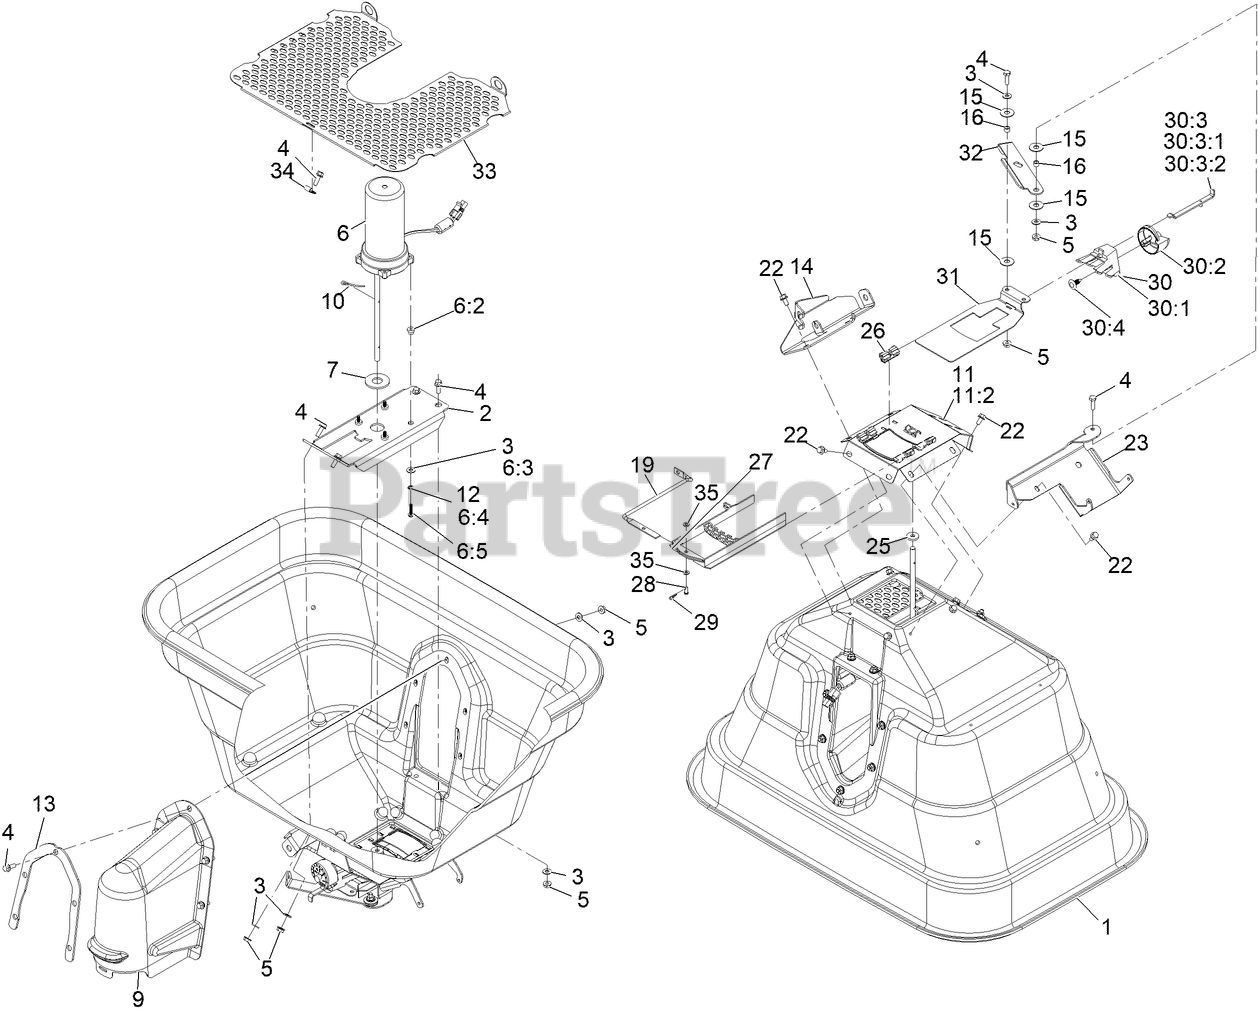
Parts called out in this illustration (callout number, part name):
1	HOPPER-SPREADER, 175 LB
2	BRACKET-MOUNT, MOTOR
3	WASHER-FLAT
4	SCREW-HH
5	NUT-HF
6	SPREADER MOTOR ASM
6:2	SPACER-FLANGED
6:3	WASHER-FLAT
6:4	WASHER-LOCK, INT
6:5	SCREW-SHWH
7	SPACER
9	COVER-MOTOR
10	WIRE-AGITATOR
11	ASM-MULCH PLATE W/ BEARING
11:2	HOPPER BOTTOM BEARING
12	WASHER-LOCK, INT
13	FLANGE-COVER, MOTOR
14	BRACKET-HOPPER, GATE CONTROLS
15	WASHER
16	SPACER
19	ROD-CONTROL, DIFFUSER
22	SCREW-HHF
23	BRACKET-LEVER, HOPPER GATE
25	WASHER-FELT
26	GUIDE-RATE, GATE
27	DIFFUSER
28	PIN-CLEVIS
29	PIN-COTTER, HAIR
30	RATE DIAL ASM
30:1	MOUNT-DIAL
30:3	RATE GATE LINK ASM
30:3:1	LINK-GATE, RATE
30:3:2	SCREW-SHOULDER, SLOTTED
30:4	FOOTPAD FASTENER
31	RATE GATE
32	LEVER-GATE
33	SCREEN-HOPPER, LARGE HOLE
33	SCREEN-HOPPER, MEDIUM HOLE
33	SCREEN-HOPPER, SMALL HOLE
34	CLAMP-LOOP
35	WASHER-FLAT
